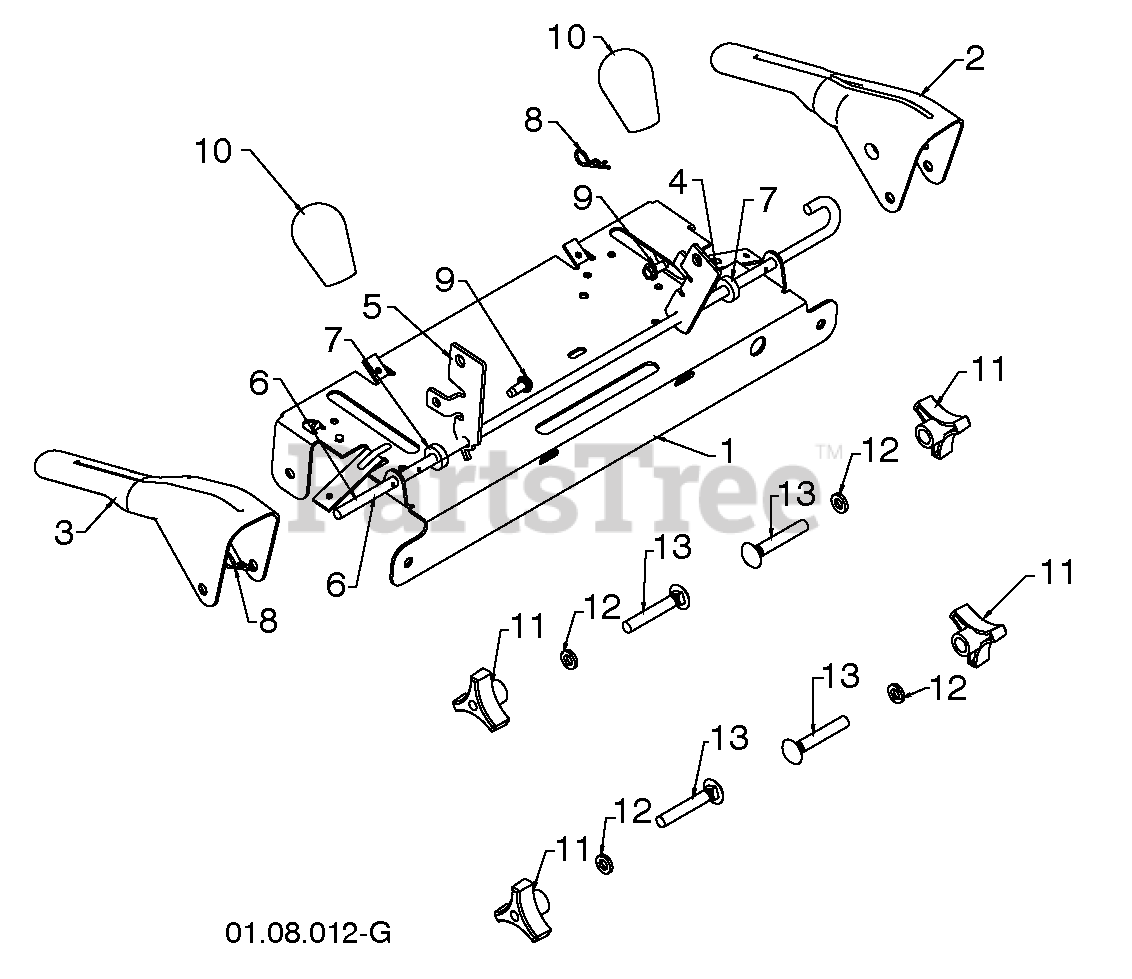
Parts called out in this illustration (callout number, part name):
1	PANEL.CONTROL.PNT.BLA
2	LEVER.CONTROL.LH.BLACK
3	LEVER.CONTROL.RH.GREY
4	ARM.TRACTION.ROD.YZ
5	ARM.IMPELLER.ROD.SNOW
6	BAIL.CONTROL.INTERLOCK
7	SPACER.CONTROL.LEVER
8	SPRING RETAINER
9	SCREW 14-20 X 5/8
10	KNOB.OVERMOLD.DS.HUSQVARNA/BLK
11	KNOB.HANDLE.3/8.TRI-POINT.BLAC
12	WASHER
13	BOLT 3/8-16 X 2-1/4
